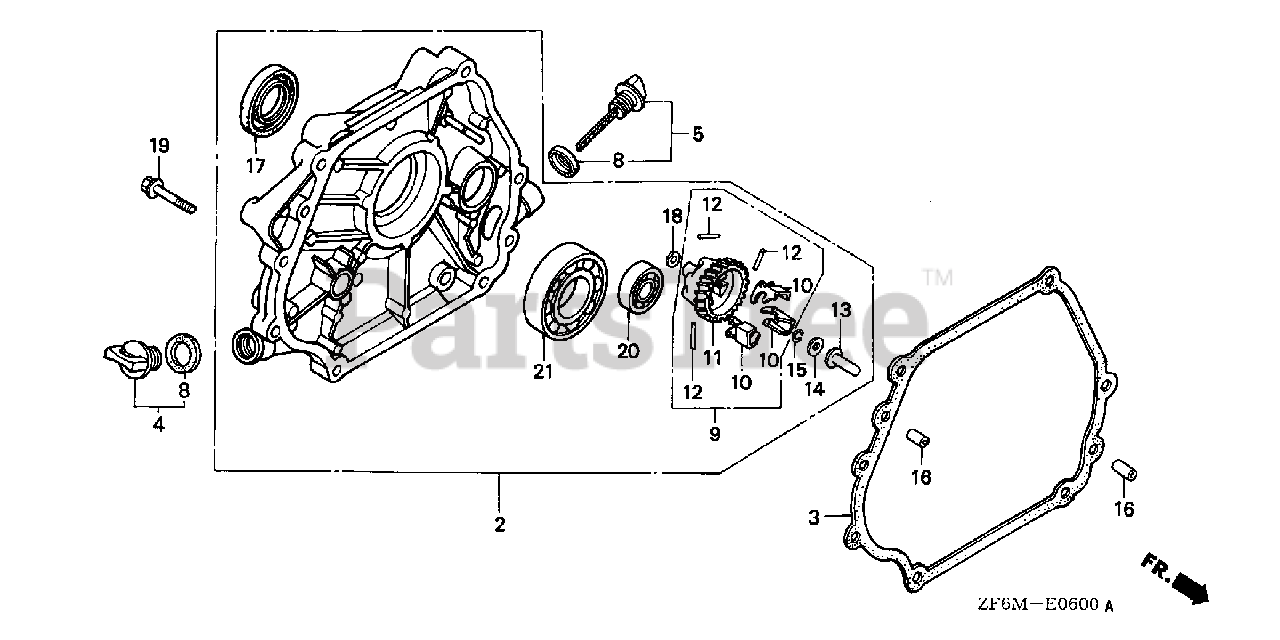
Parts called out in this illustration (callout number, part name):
2	COVER ASSY., CRANKCASE (Q-TYPE)
3	GASKET, CASE COVER
4	CAP ASSY., OIL FILLER
5	CAP ASSY., OIL FILLER
8	GASKET, OIL FILLER CAP
9	GOVERNOR ASSY.
10	WEIGHT, GOVERNOR
11	HOLDER, GOVERNOR WEIGHT
12	PIN, GOVERNOR WEIGHT
13	SLIDER, GOVERNOR
15	CLIP, GOVERNOR HOLDER
16	PIN, DOWEL (8X12)
17	OIL SEAL (35X52X8)
18	WASHER, PLAIN (6MM)
19	BOLT, FLANGE (8X40)
20	BEARING, RADIAL BALL (6202)
21	BEARING, RADIAL BALL (6207)
